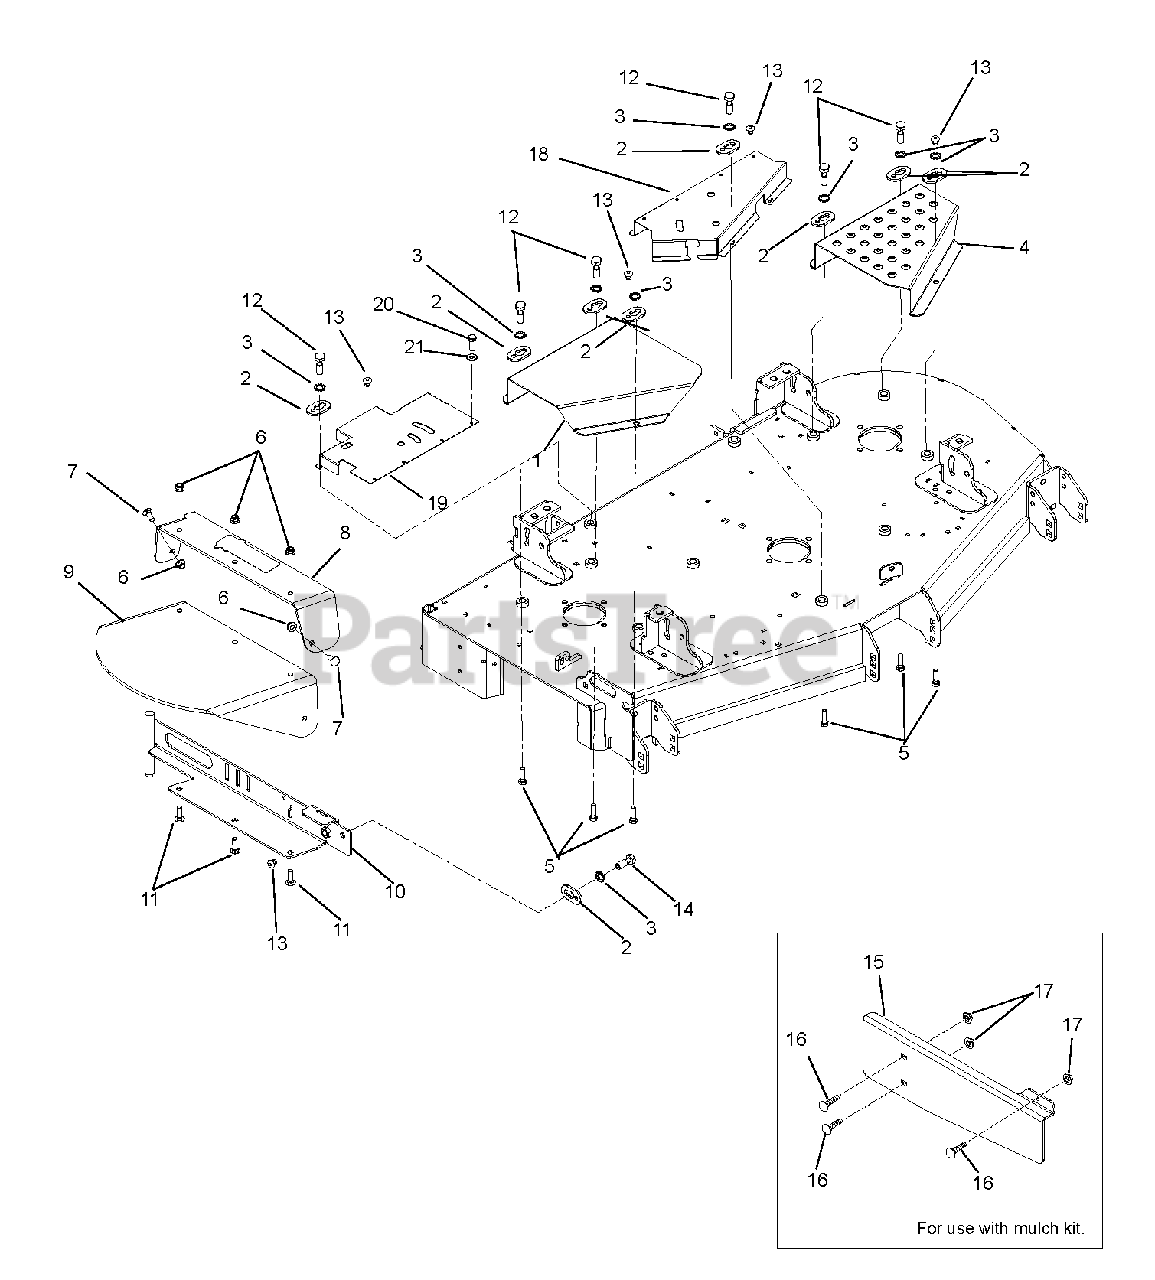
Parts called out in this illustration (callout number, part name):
1	Guard, Right Hand PT200 CE Belt
2	Keeper, Bolt
3	Washer, Locking External .391 x .682 x .036
4	Guard, Left Hand PT200 CE Belt
5	Bolt, Hex .38-16 x 1.25 Grade 5
6	Nut, Locking Nylon Flange .38-16
7	Bolt, Round Head Square Neck .38-16 x 1.00 Grade 5
8	Support, Rubber Discharge Chute
9	Chute, Rubber Discharge
10	Weldment, 52" Discharge Chute Mounting, CE
11	Bolt, Round Head Square Neck .38-16 x 1.25 Grade 5
12	Bolt, Hex .38-16 x 1.25 Grade 5 Captive
13	Rivet, Pip .187 YZ
14	Bolt, Hex .38-16 1.25 Grade 5 Captive
15	Cover, Discharge 52" CE
16	Bolt, Round Head Square Neck .31-18 x 1.00 Grade 5 YZ
17	Nut, Locking Nylon Flange .31-18 YZ
18	Weldment, Front Belt Shield
19	Shield, Belt Rear
20	Bolt, Hex .25-20 x .75 Grade 5 YZ
21	Washer, Flat Steel .231 x .62 x .065 YZ
